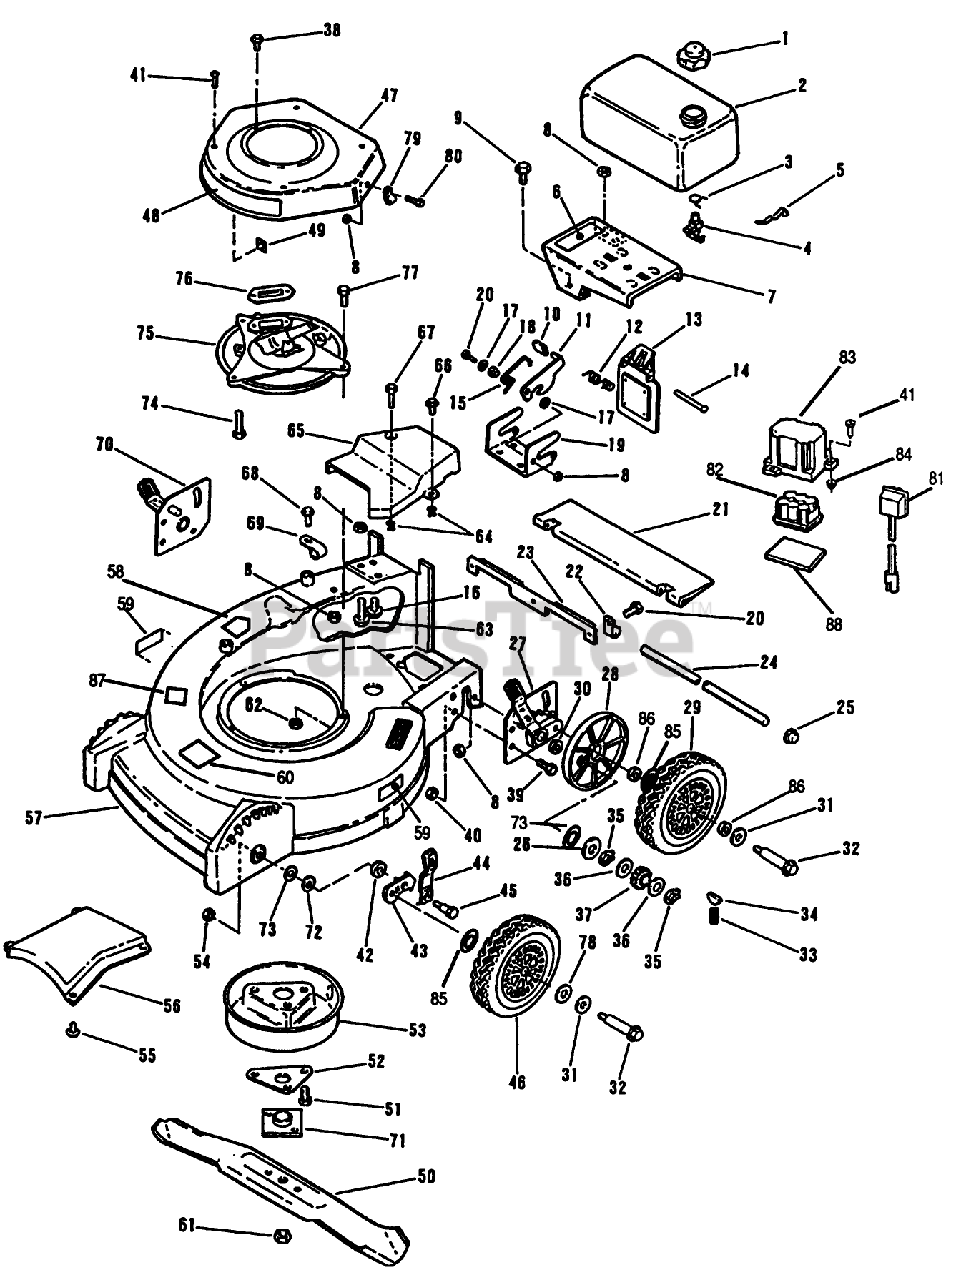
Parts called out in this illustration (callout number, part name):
1	FUEL CAP & INSERT
3	CLAMP - HOSE S
4	VALVE&SCREEN SM
5	SPRING
7	BRACKET - TANK
8	LOCKNUT E
10	KNOB (S&R)
12	SPRING ASOC
14	ROD (RB&W)
15	SPRING
16	SCREW HEX WASHER
21	T/SHIELD SM&P
26	THRUST WASHER
27	HEIGHT ADJ. AY.
30	WASHER
31	SPACER
32	BOLT WHEEL
33	SPRING
34	KEY
35	RET RING
36	SPACER/GR ALGHNY
37	PINION BROCKWAY
38	SCREW SEMS SM
39	SCREW - HEX
40	NUT-LOCK F
41	SCREW - SELF TAPPING
42	WASHER
44	SPRING ARM ASM
45	BOLT
46	WHEEL&TIRE 8" TRI
49	PUSHNUT F
50	20" Blade
51	SCREW
52	SUPPORT F
53	MUFFLER COVER F
54	LOCKNUT
56	BAFFLE CHUTE PL
61	NUT-BLADE
62	NUT-LOCK F
63	SCREW
66	SCREW
68	SCREW LAWRENCE
70	HT. ADJ. AY.
71	PLATE AND COLLAR ASM
72	WASHER
73	WASHER
74	SCREW V
77	SCREW-HH
78	LOCKNUT
84	NUT-CLIP
85	WASHER WROUGHT
86	WASHER-FELT
88	PAD-BATTERY
